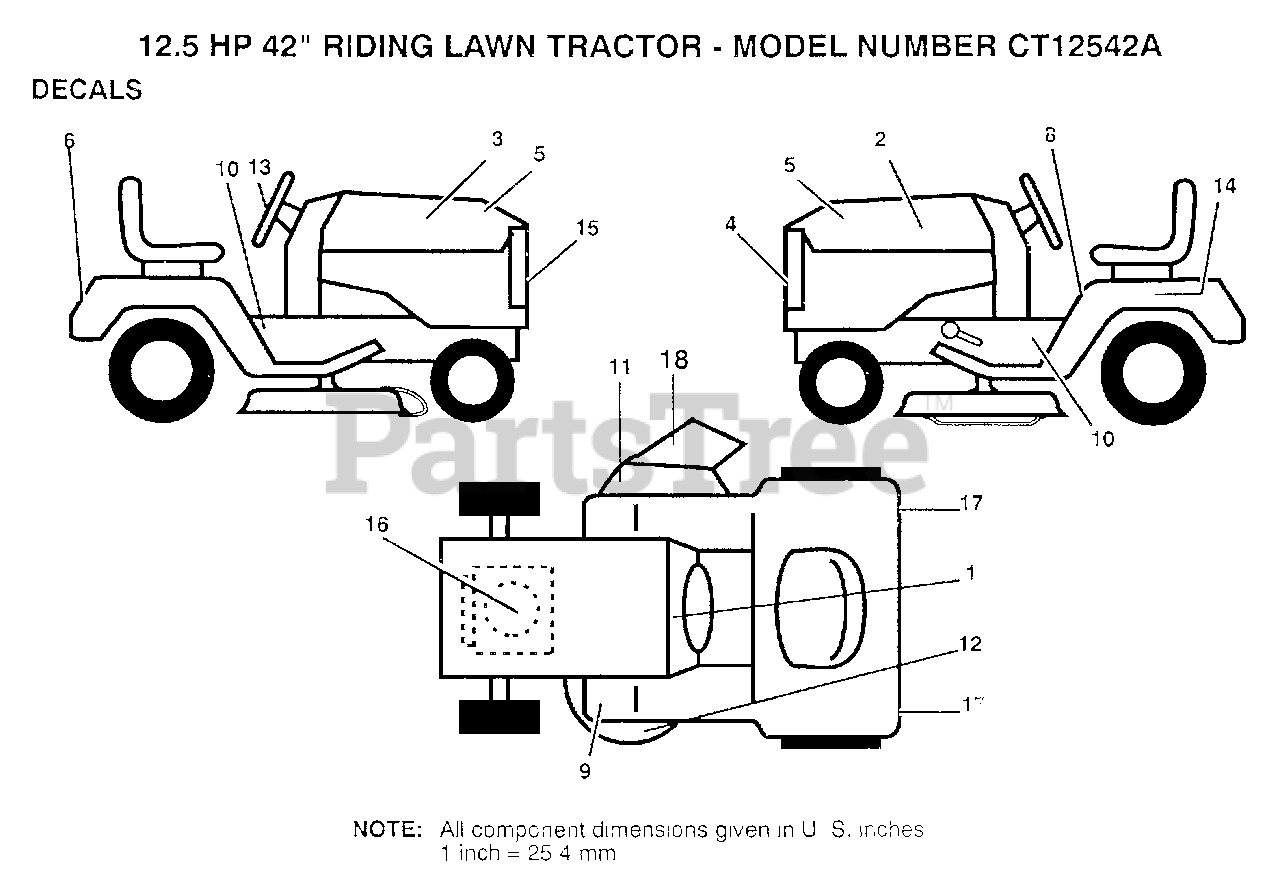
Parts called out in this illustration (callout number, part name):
5	"DECAL,HOOD"
6	"DECAL,FENDER"
8	DECAL
9	DECAL T
10	CHASSIS DECAL
11	DECAL WARNING
12	DECAL YT
13	"DECAL,STR WHL"
14	DECAL
17	REFLECTOR-TAIL YT
18	DECAL WARNING
